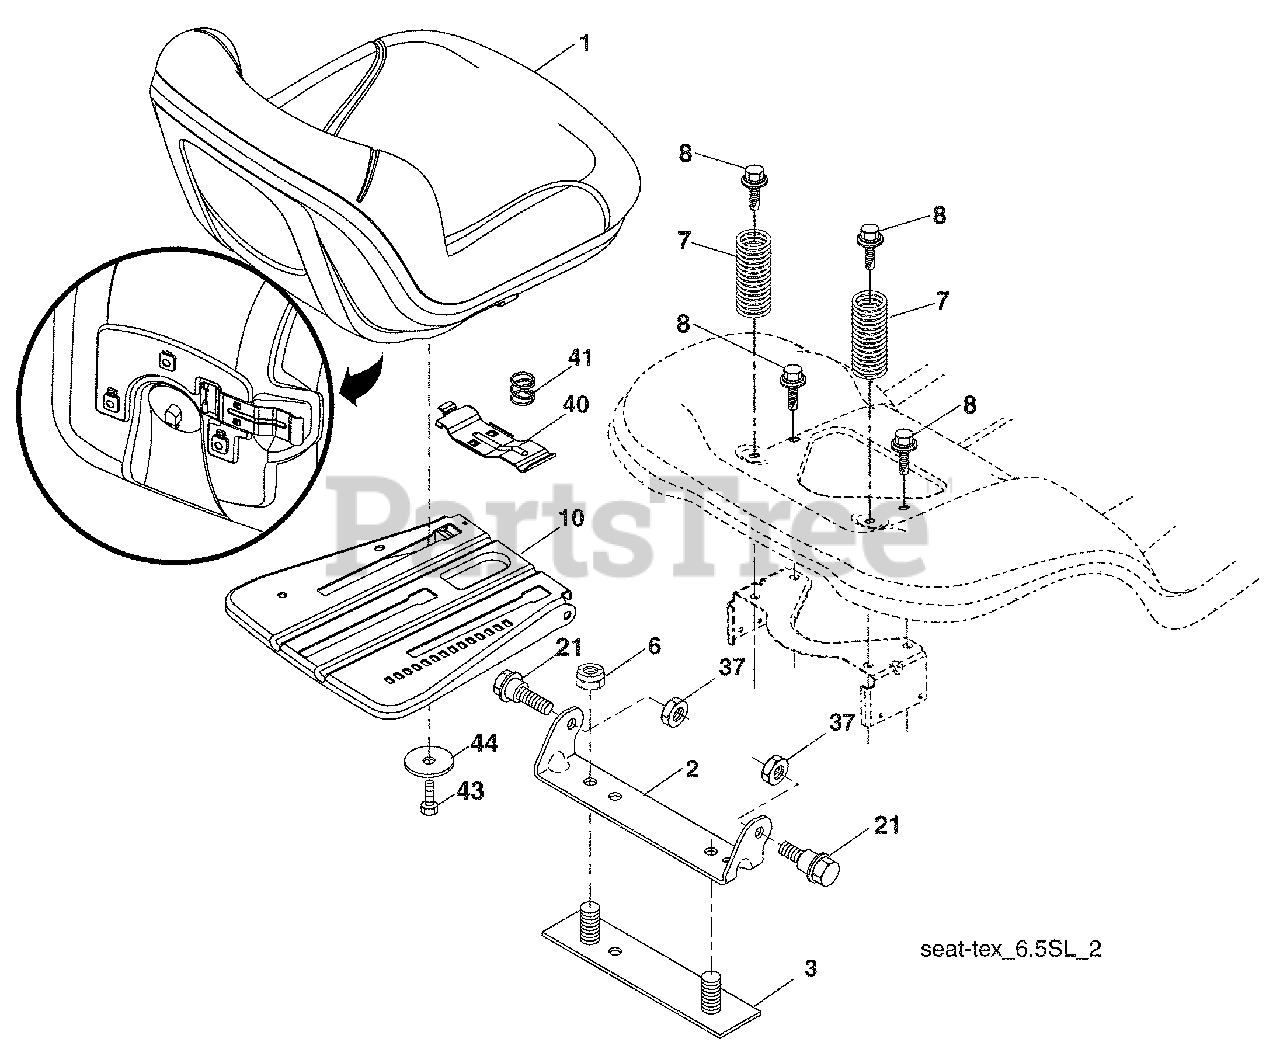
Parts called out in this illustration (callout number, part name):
1	Seat
2	Bracket Pivot Fender
3	Strap, Asm Fender
6	Nut, Lock W/Ins. 3/8-16 unc
7	Spring, Seat Cprsn
8	Bolt 5/16-18 unc x 3/4 w/Sems
10	Pan, Seat
21	Bolt, Shoulder 5/16-18
37	Nut, Lock 5/16-18 unc
40	Handle Slide Seat
41	Spring Latch Seat
43	Bolt Fin Hex 3/8-16 unc x 3/4
44	Washer 13/32 x 2-3/8 x 12 Ga.
